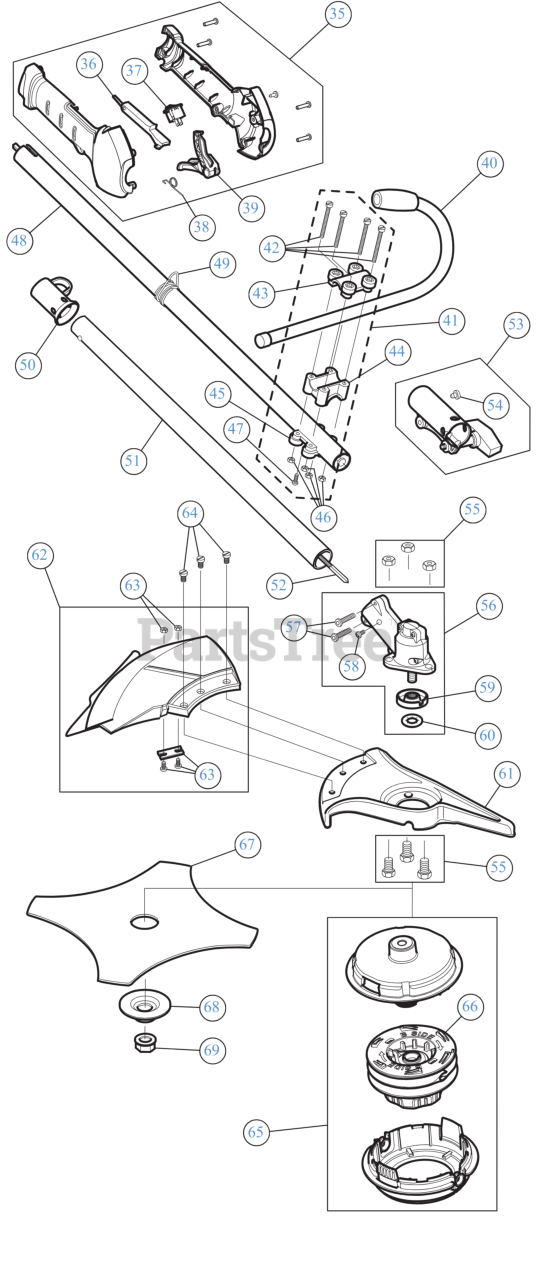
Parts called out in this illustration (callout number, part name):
35	THROTTLE GRIP ASSEMBLY
36	LEVER LOCK OUT
37	SW, MOMENTARY ON/O
38	TRIGGER SPRING
39	THROTTLE TRIGGER
40	HANDLE ASSEMBLY-JAY
41	HANDLE BRACKET ASSEMBLY
42	CLAMP SCREW
43	HANDLE UPPER CLAMP
44	HANDLE MIDDLE CLAMP
45	HANDLE LOWER CLAMP
46	NUT-CLAMP
47	SCREW, 8-32 x .312 P
48	BOOM ASSEMBLY UPR
49	CLAMP-SHOULDER STR
50	HANGER
51	ASSEMBLY, LOWER DRIVE S
52	LOWER DRIVE SHAFT
53	COUPLER ASSEMBLY
54	SCREW, 10-32X.250 TA
55	SCREW SET-GUARD MT
56	GEARBOX ASSEMBLY
57	SCREW #
58	SCREW, 8-32 x .312 P
59	SPACER-GEARBOX
60	PALNUT:3/8" DIAM
61	SHIELD-BLADE CAST
62	SHIELD ASSEMBLY WITH BLADE
63	BLADE ASSEMBLY
64	SCREW-GUARD MTG PK
65	HEAD ASSEMBLY .105 (LIB RED)
66	BUMP KNOB
67	BLADE 4-TOOTH
68	WASHER-BLADE CLAMP BRUSH CUT
69	BLADE LOCK NUT
